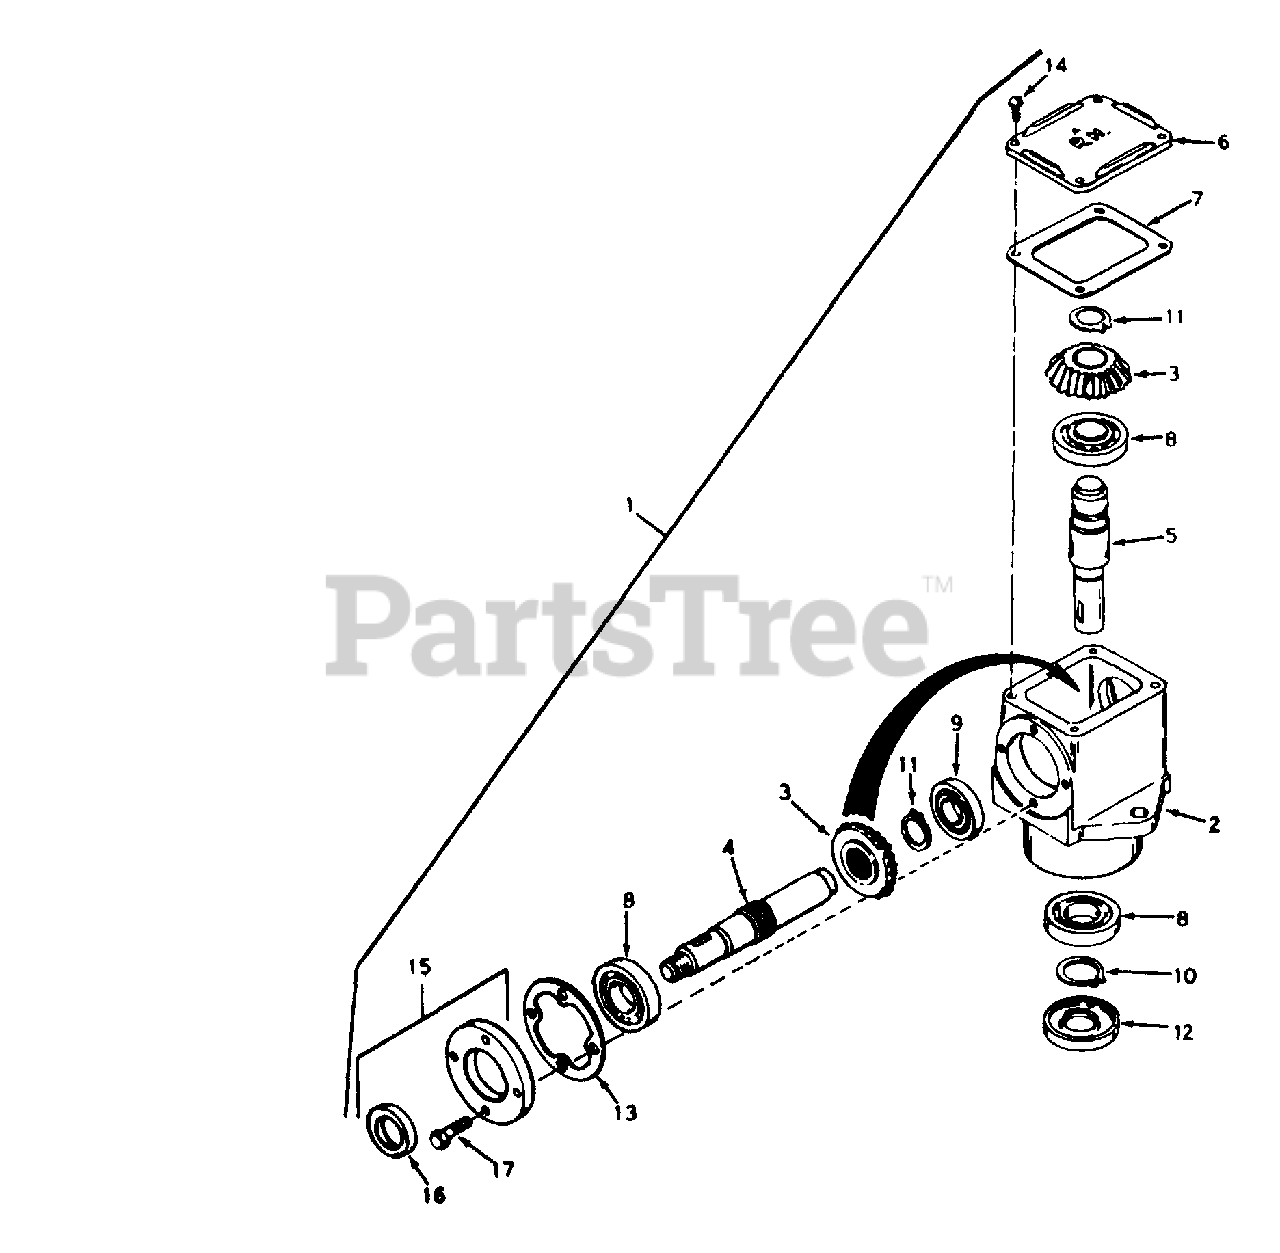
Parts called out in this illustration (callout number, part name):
1	Head Ass'y. R.H.
2	Housing, Right Angle Drive
3	Gear, Miter
4	Shaft, Input
5	Shaft, Output
6	Cover, Right Hand
7	Gasket, Cover
8	Bearing, Ball
9	Bearing, Ball
10	Ring, Snap
11	Ring, Snap
12	Seal, Oil
13	Gasket, Cap
14	Screw, Rd. Hd. Self-Tap. 10-24 x 1/2
15	Cap & Seal Ass'y., Retainer
16	Seal, Oil
17	Screw, Hex Hd. 1/4-20 x 7/8
